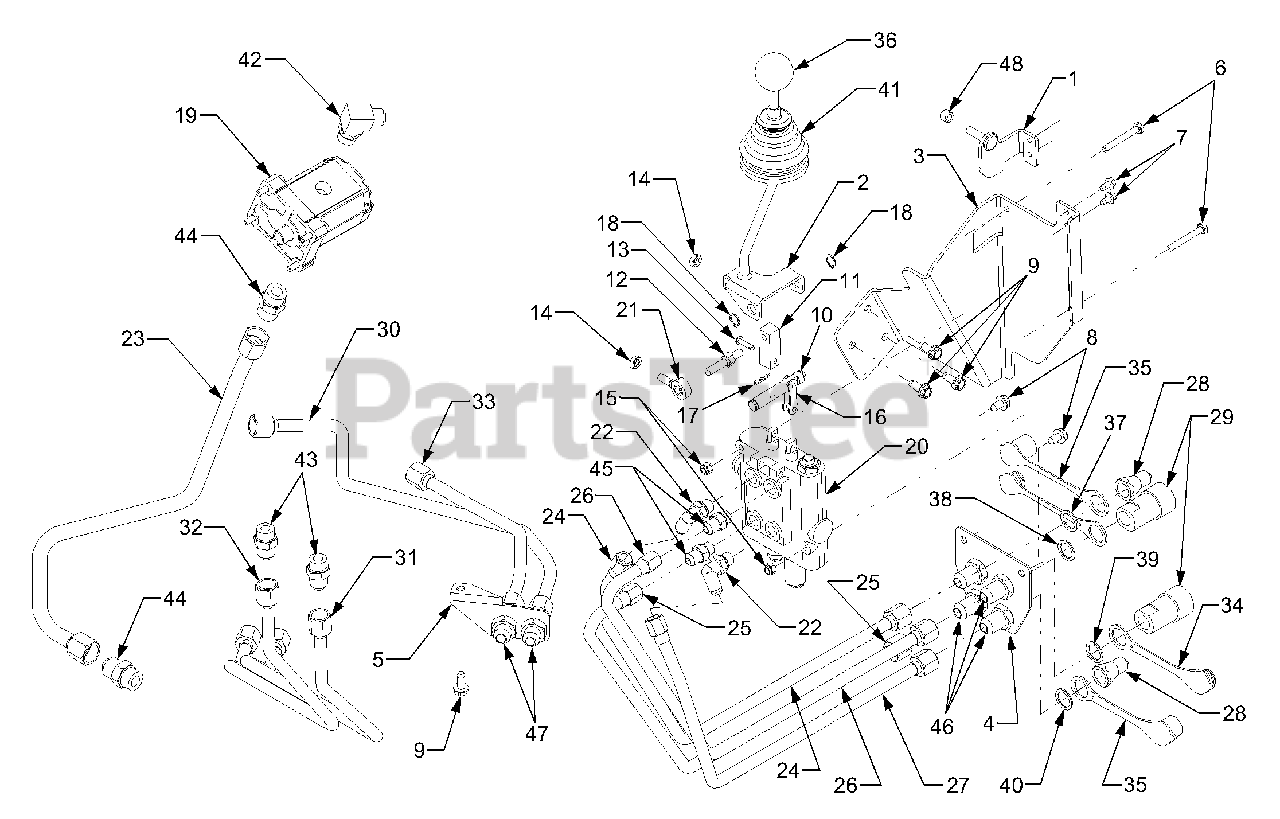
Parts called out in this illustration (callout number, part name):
1	Pivot Bracket Assembly
2	Valve Handle Assembly
3	Loader Valve Mount Bracket
4	Fitting Mount Plate
5	Rear Fitting Mount Plate
6	Hex Screw, 1/4-20, 2.00, Gr5
7	Hex Wash. Hd. Tapp Screw 1/4-20 x .50
8	Hex Wash. Hd. Tapp Screw 5/16-18 x .625
9	Hex Wash. Hd. Tapp Screw 5/16-18 x .75
10	Valve Pivot Shaft
11	Valve Spool Link
12	Ball Joint Pivot Stud
13	Clevis Pin, .199 x .8125
14	Jam Nut, 5/16-24, Gr2
15	Hex Lock Nut, 1/4-20, Gr8, Nylon
16	Chain Link
17	Internal Cotter Pin
18	Snap Ring, .5
19	Auxiliary Hydraulic Pump
20	Loader Control Valve
21	Ball Joint, .3125 Id x 5/16-24
22	Fitting, 90° 6-6 Orb
23	Tube, Tandum Pump Suction
24	Tube, Boom Lift Loader
25	Tube, Return Boom
26	Tube, Lift Bucket
27	Tube, Return Bucket
28	Coupling, Male Hydraulic, 3/8-18
29	Coupling, Female Hydr. 3/8-18
30	Tube, Auxiliary Pump Pressure
31	Tube, Valve Pressure
32	Tube, Valve Return
33	Tube, Valve Return
34	Plug, Hydraulic Coupler - Male
35	Plug, Hydraulic Coupler - Female
36	Knob, 1.625 Dia x 3/8-16 Thd
37	Washer, Indicator - Red
38	Washer, Indicator - Yellow
39	Washer, Indicator - Green
40	Washer, Indicator - Blue
41	Joystick Boot
42	Fitting, 90° -8 Orb
43	Fitting, Straight -8 Orb
44	Fitting, Straight
45	Fitting, Straight - 6 Orb
46	Fitting, Bulkhead 3/4-16 x 3/8-18
47	Fitting, Bulkhead 3/4-16 x 3/4-16
48	Spacer, .34 ID x .5 OD x .31
